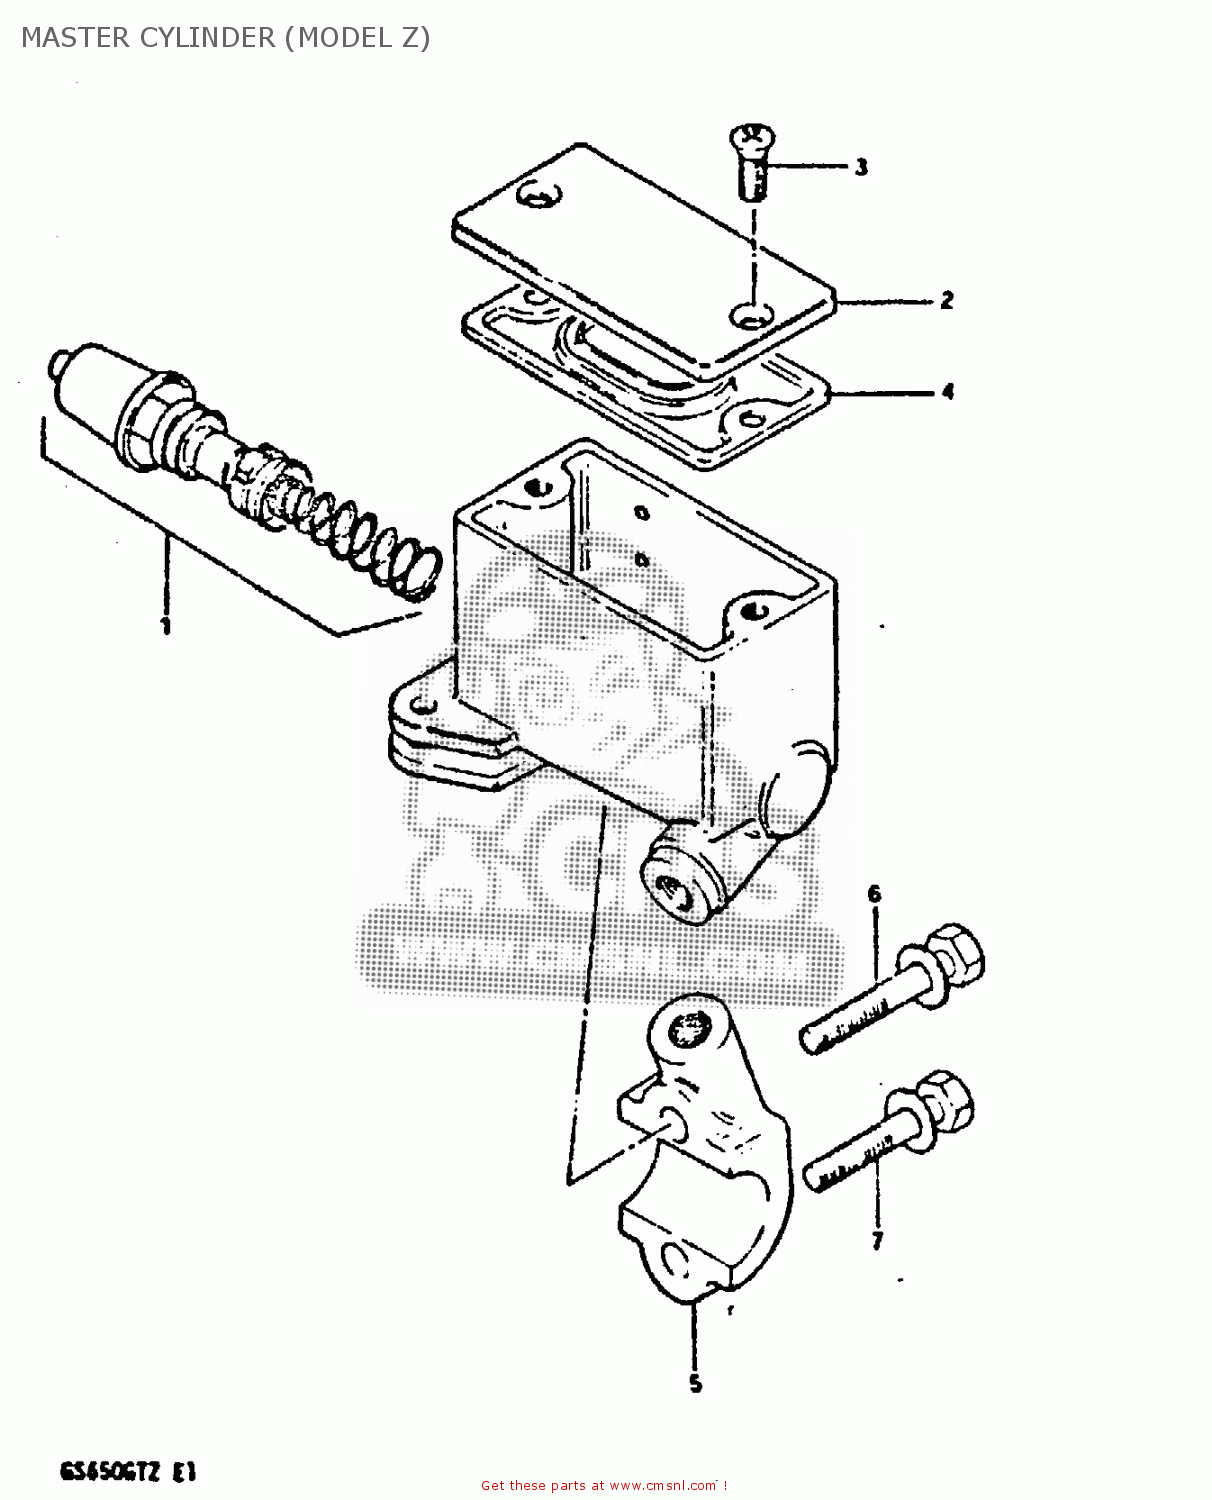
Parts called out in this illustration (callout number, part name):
1	PISTON & CUP SET
2	CAP
3	SCREW,RESERVOIR CAP
4	DIAPHRAGM,MASTER CYLINDER
5	HOLDER
6	BOLT,MASTER CYLINDER H
7	BOLT, LOWER
